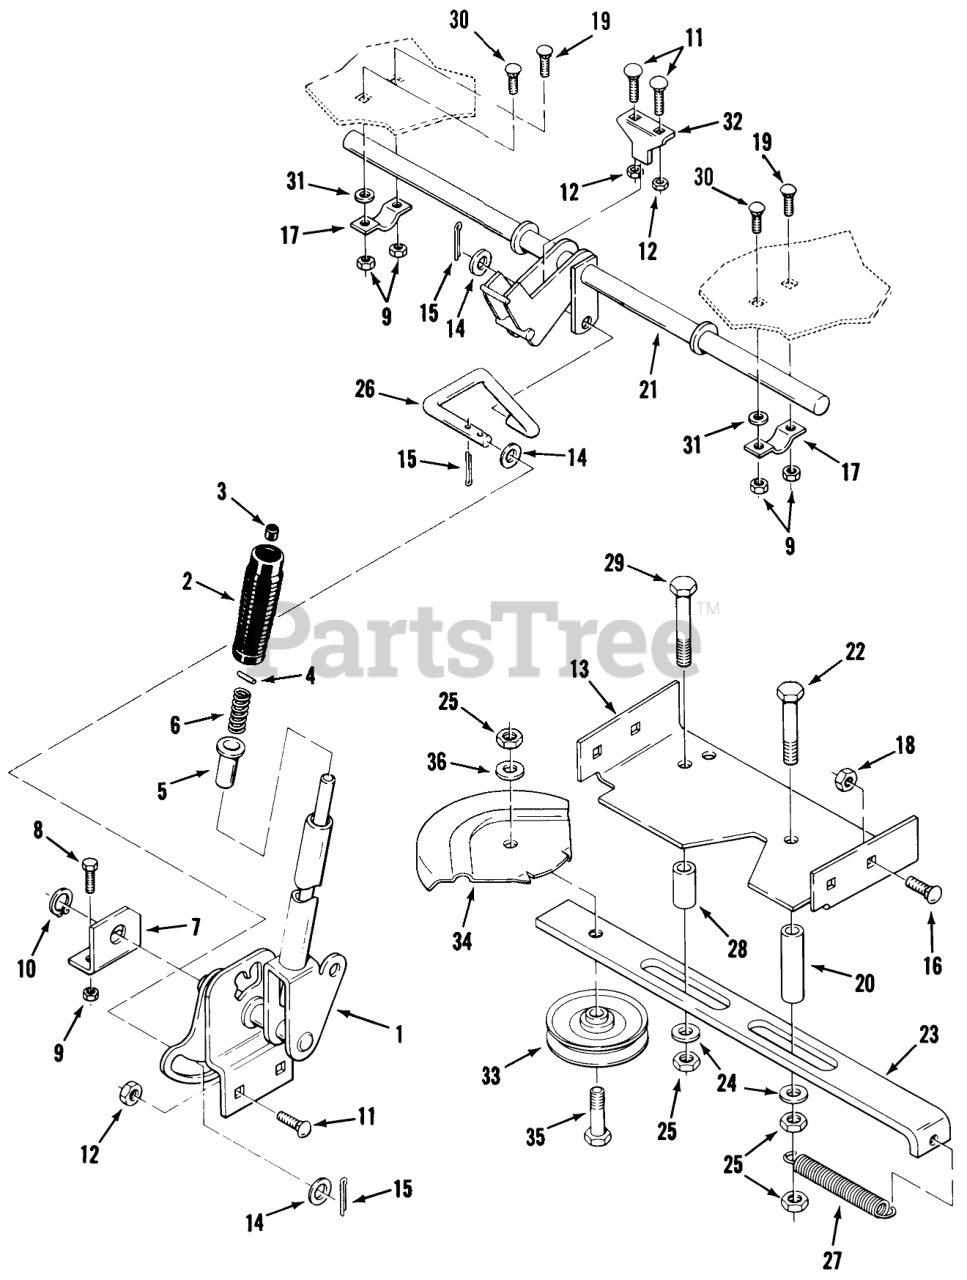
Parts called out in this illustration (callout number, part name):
1	Lift Lever
2	HANDGRIP
3	CAP-ROD, PLUNGER
4	PIN-SPIROL
5	RETAINER-SPRING
6	SPRING-COMPRESSION
7	BRACKET-INNER R
8	Bolt
9	Nut
10	Snap Ring
11	Bolt-Carriage
12	NUT
13	ASS'Y-FRAME BRACE R
14	Washer
16	Bolt
17	CLAMP
18	Nut
19	Bolt
20	SPACER-2.0 LG R
21	ASSY REAR LIFT R
22	Bolt
24	Washer
25	NUT
26	ROD LIFT R
27	SPRING-EXTENSION
28	SPACER-2.0 LG R
29	Screw-Hex. Hd.
30	Bolt-Carriage
31	Washer
32	BRACKET STOP
33	PULLEY IDLER
34	GUARD-IDLER PULLE R
35	Bolt
36	Washer
